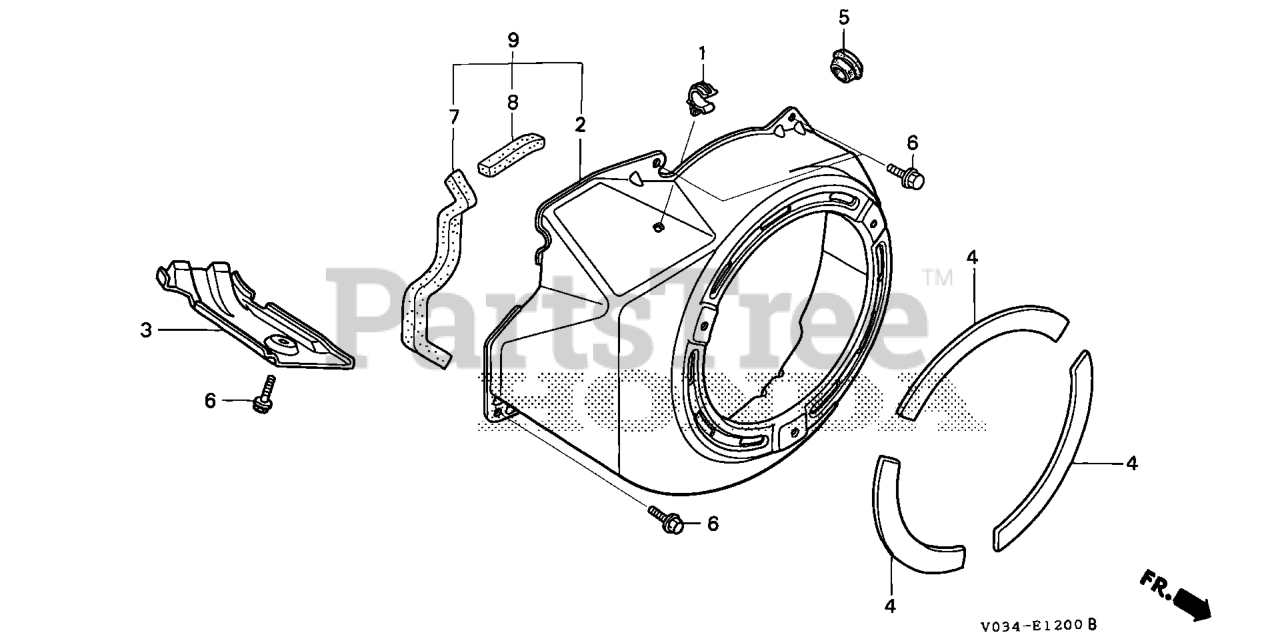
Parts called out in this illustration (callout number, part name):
1	CLIP, TUBE
2	COVER, FAN *R280* (POWER RED)
4	SEAL, RECOIL
5	GROMMET, DRAIN HOLE
6	BOLT, FLANGE (6X12) (CT200)
7	SEAL, RECOIL
8	SEAL, FAN COVER
9	COVER, FAN *R280* (POWER RED)
